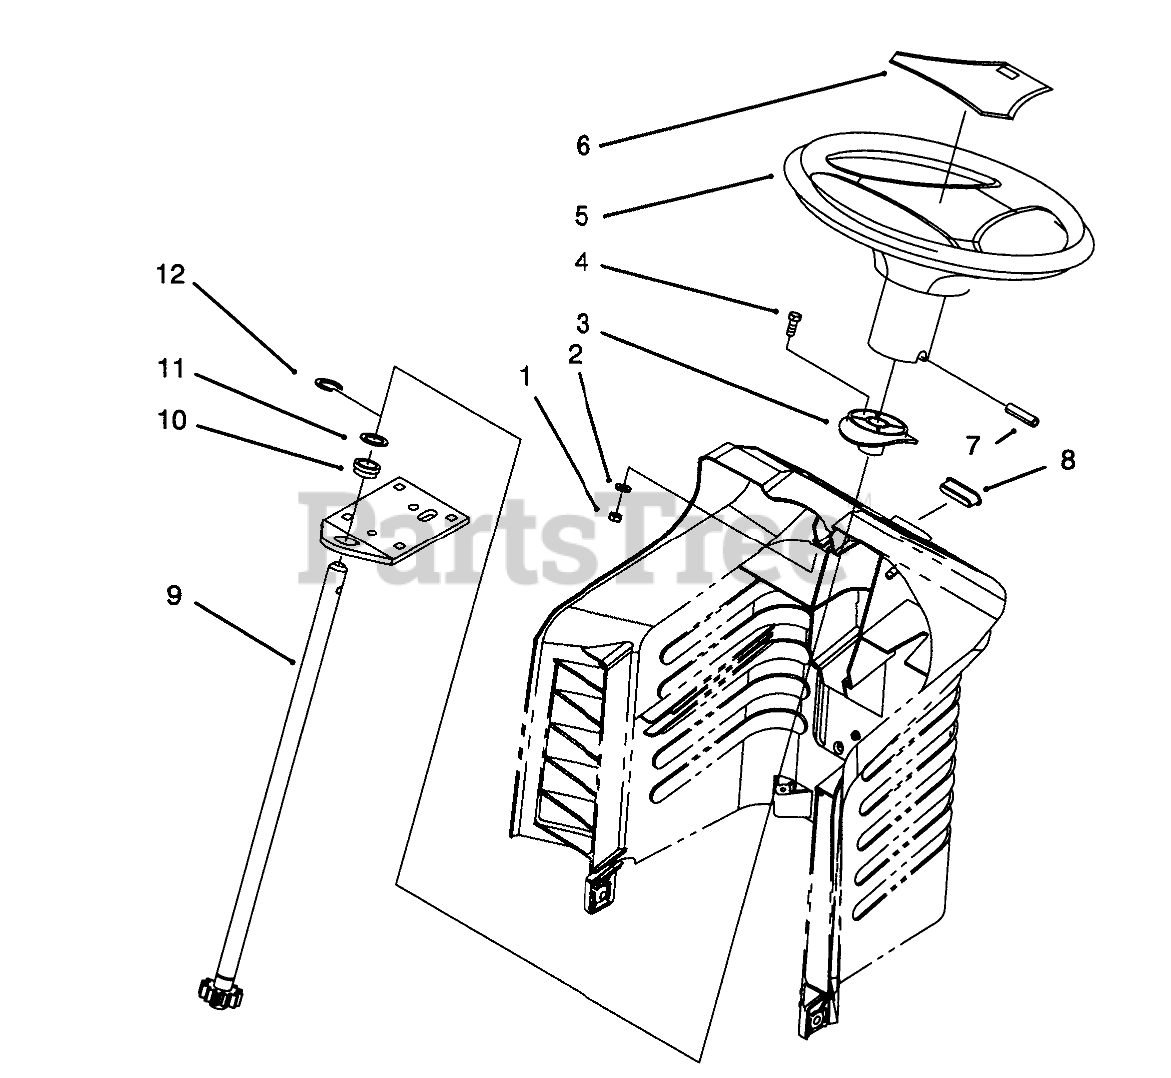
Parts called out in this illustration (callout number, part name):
1	NUT-LOCK, NI
2	WASHER-FLAT
3	BUSHING-SLIDING
4	SCREW-HH
5	Wheel-Steering (Incl. Ref. #6)
6	COVER-WHEEL
7	PIN-ROLL
9	SHAFT-STEERING, LONG
10	BEARING-FLANGE
11	WASHER-THRUST
12	E-RING
